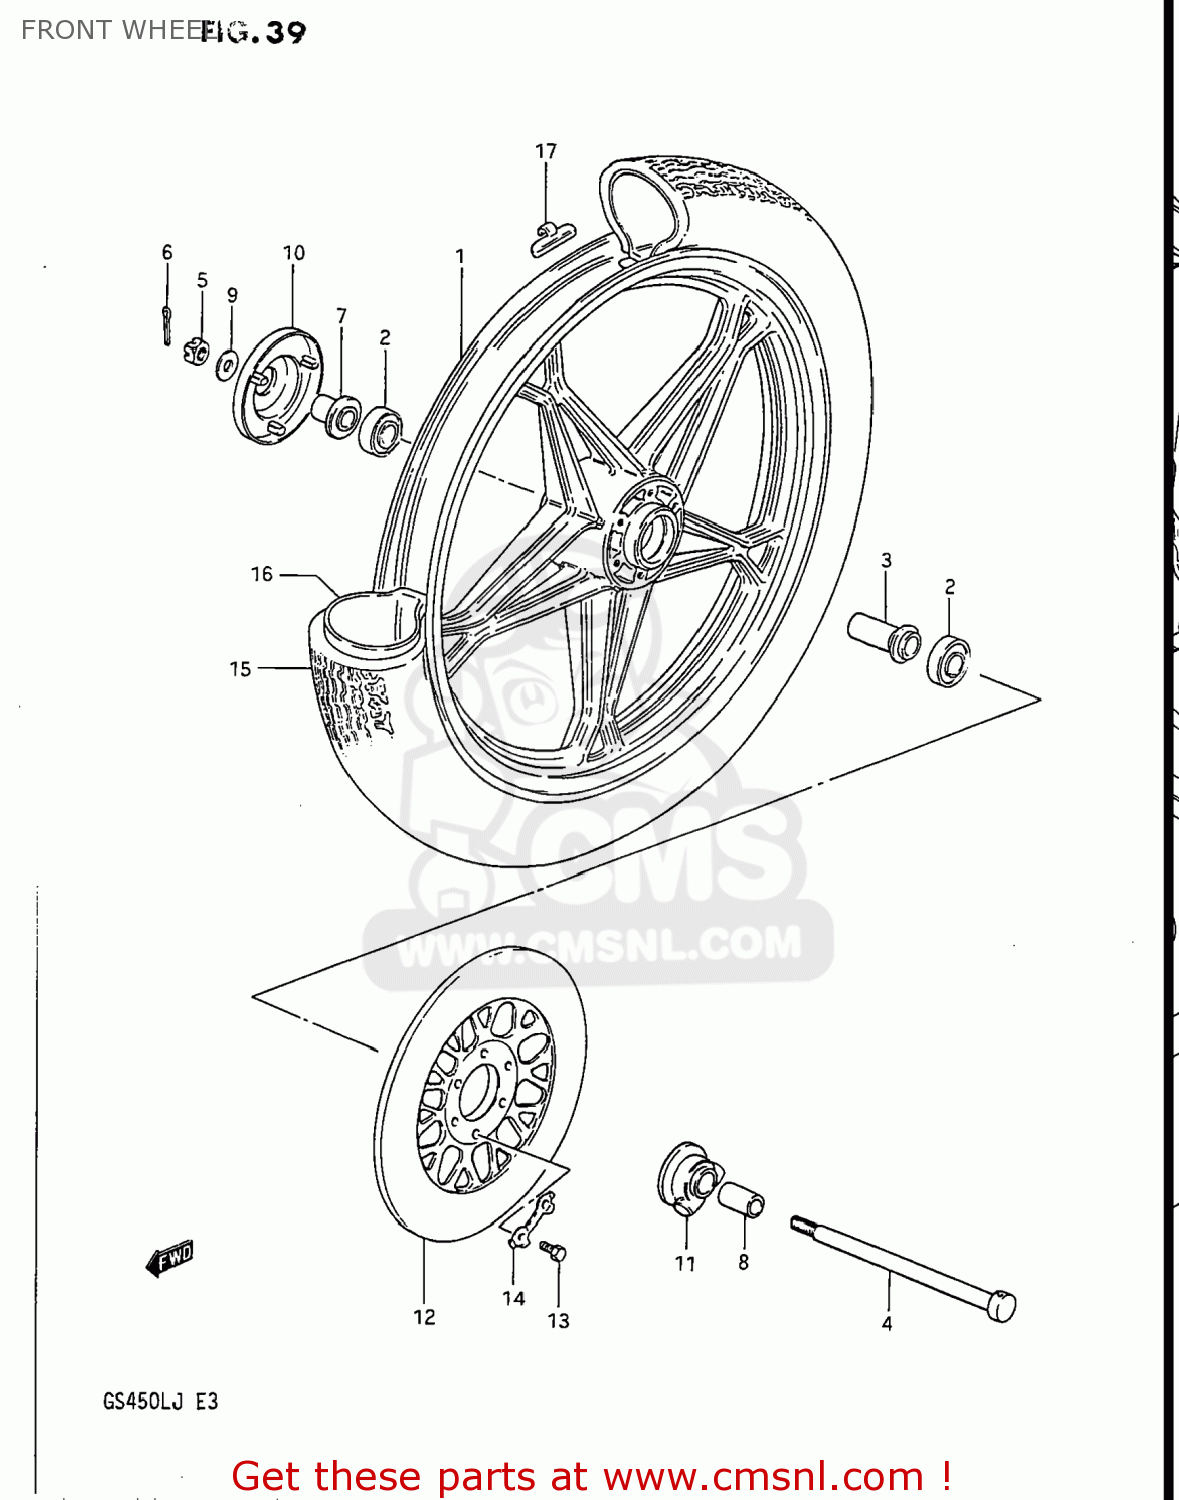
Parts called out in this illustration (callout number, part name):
1	CASTING WHEEL,FRONT 1.85
2	BEARING
3	SPACER,FR HUB BEARING
4	AXLE,FRONT
5	NUT 12MM
6	COTTER PIN
7	SPACER,FR HUB BEARING,R
8	SPACER(15X22X30)
9	WASHER
10	COVER,FR HUB,R
11	BOX ASSEMBLY,SPEEDOMETER GEAR
12	DISC,FR BRAKE
13	BOLT(8X25)
14	WASHER
15	TIRE
16	TUBE 2.75-19 070-483MM
17	BALANCER,WHEEL
